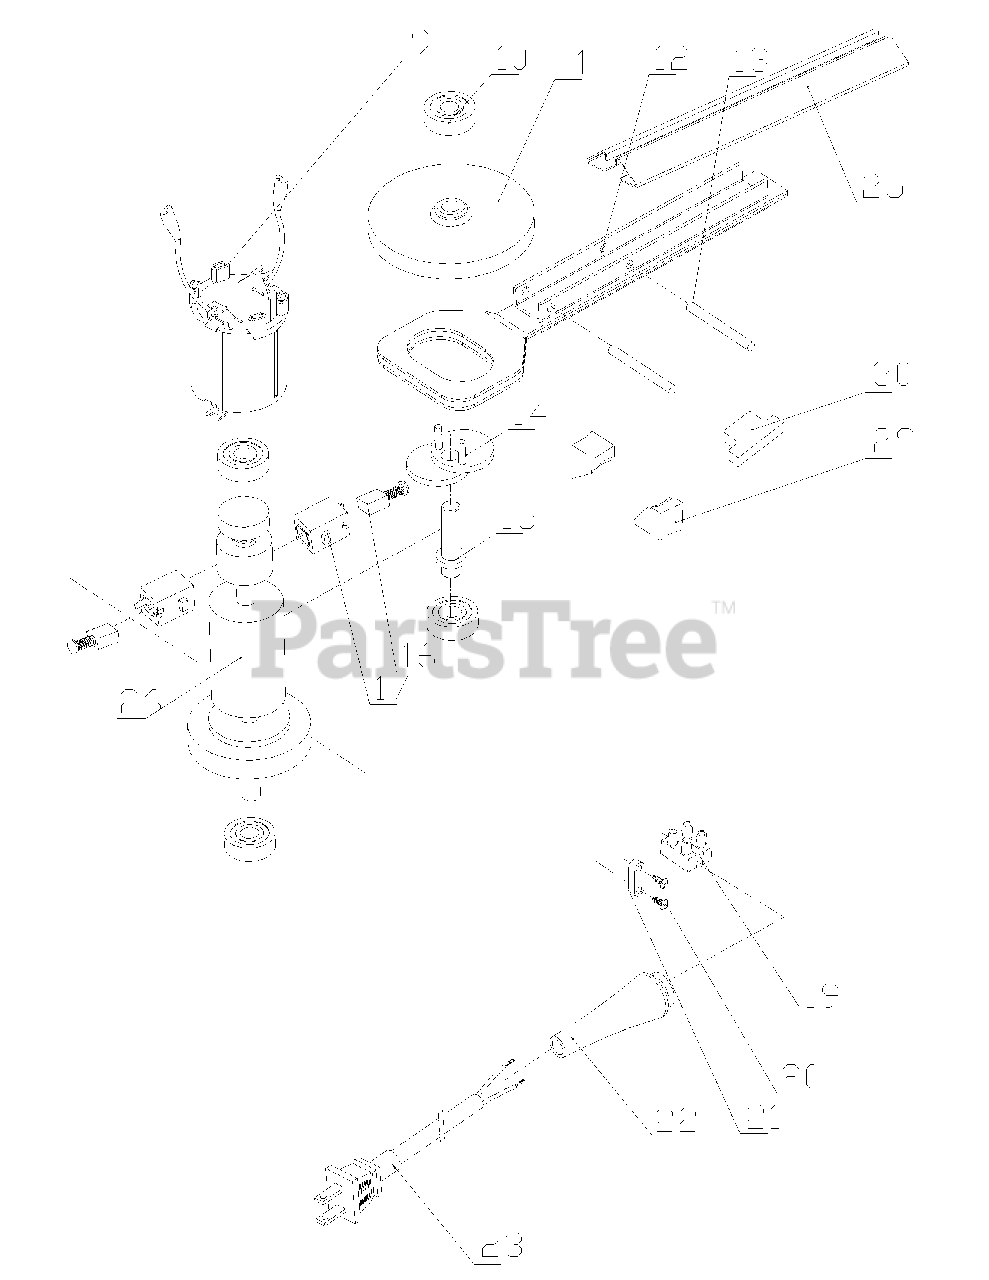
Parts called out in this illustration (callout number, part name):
7	HOUSING (L)
9	FIELD ASS'Y
12	18" BLADE
14	ECCENTRIC SHAFT
15	OUTPUT SHAFT
17	BRUSH HOLDER
18	HOUSING (R)
19	TERMINAL BLOCK
21	STRAIN RELIEF
22	CORD GUARD
23	POWER CORD
25	BLADE COVER
31	LABEL (R)
32	LABEL (L)
